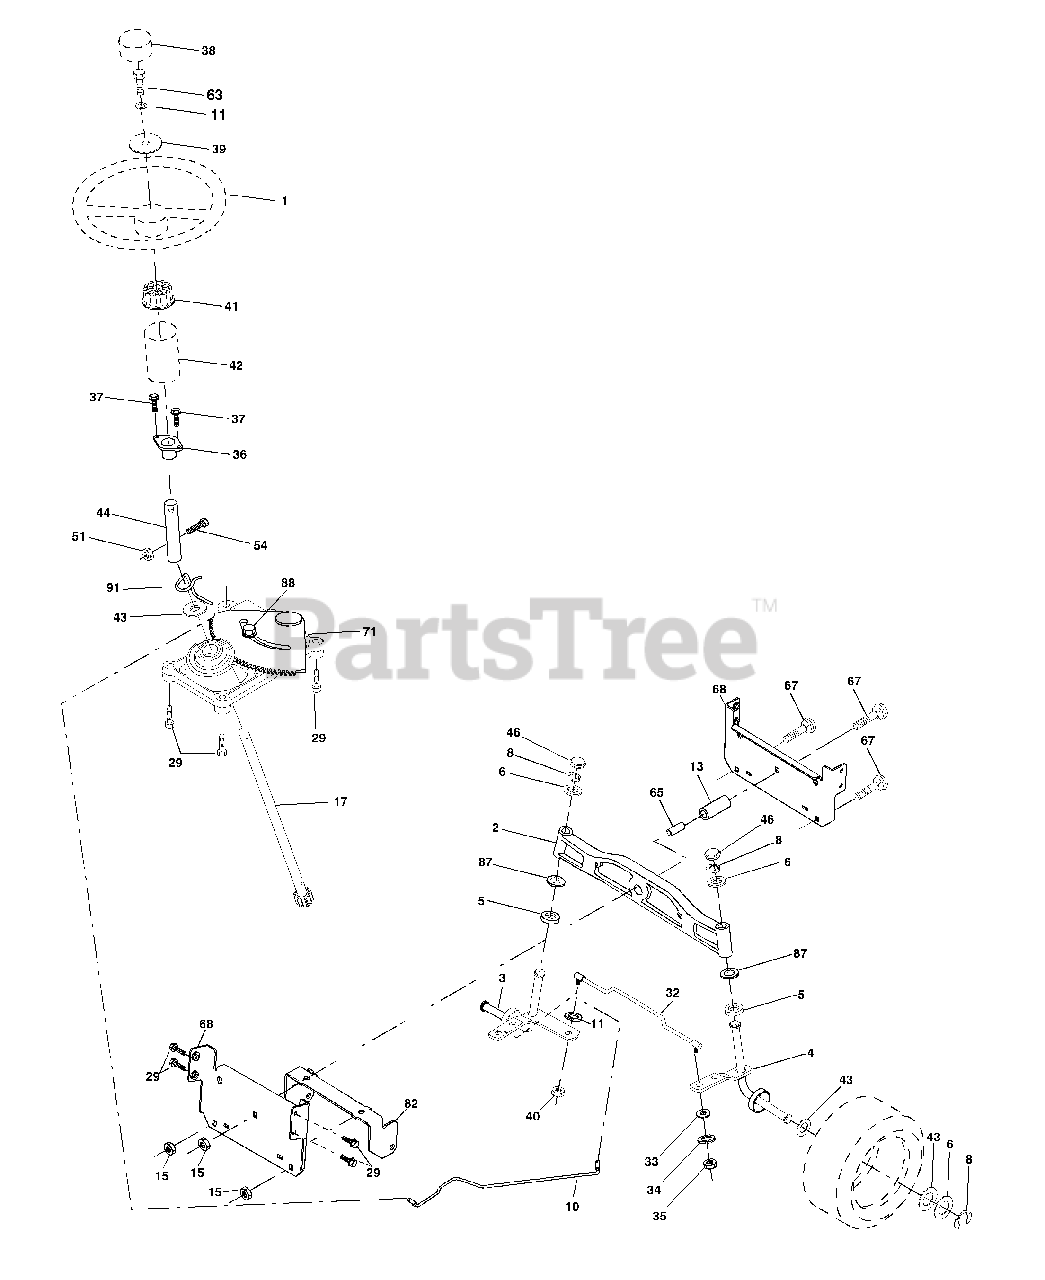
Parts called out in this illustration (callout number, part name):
1	Wheel Steering
2	Axle Cast Lt Machined
3	Spindle Asm LH
4	Spindle Asm RH
5	Bearing Race Thrust Harden
6	Washer 25/32 X 1-5/8 X 16 Ga
8	Ring Klip #t5304-75
11	Washer Lock Hvy Hlcl Spr 3/8
13	Spacer Brg Axle Front
15	Nut Hex Flange Lock
17	Shaft Asm Strg
29	Screw 3/8-16x3/4
32	Rod Tie Ball J
33	Washer 11/32 x 3/4 x 16 Ga.
34	Washer Lock Hvy Helical 5/16
35	Nut Crown Lock 5/16-24Unf
36	Bushing Strg
38	Insert Cap Strg Wh
39	Washer 13/32 x 1-1/20 x 11 Ga
40	Lock nut
41	Adaptor Wheel Strg
42	Boot Steering Shaft
43	Washer 25/32 X 1 1/4 X 16 Ga
44	Extension Steering Shaft LR/LT
46	Cap Spindle Fr Top Blk
51	Nut Lock Hex w/Ins 5/16-18
54	Bolt Fin Hex 5/16-18 Unc x 1-1/4
63	Bolt Fin Hex 3/8-16unc x 1 Gr. 5
65	Spacer Brace Axle
67	Bolt Rdhd Sq 3/8-16 x 2-1/4
68	Axle, Brace
71	Steering Asm
82	Bracket Susp Chassis Front
87	Washer Flat .781 x 1-1/2 x .14
88	Bolt Shoulder 7/16-20
91	Clip Steering
